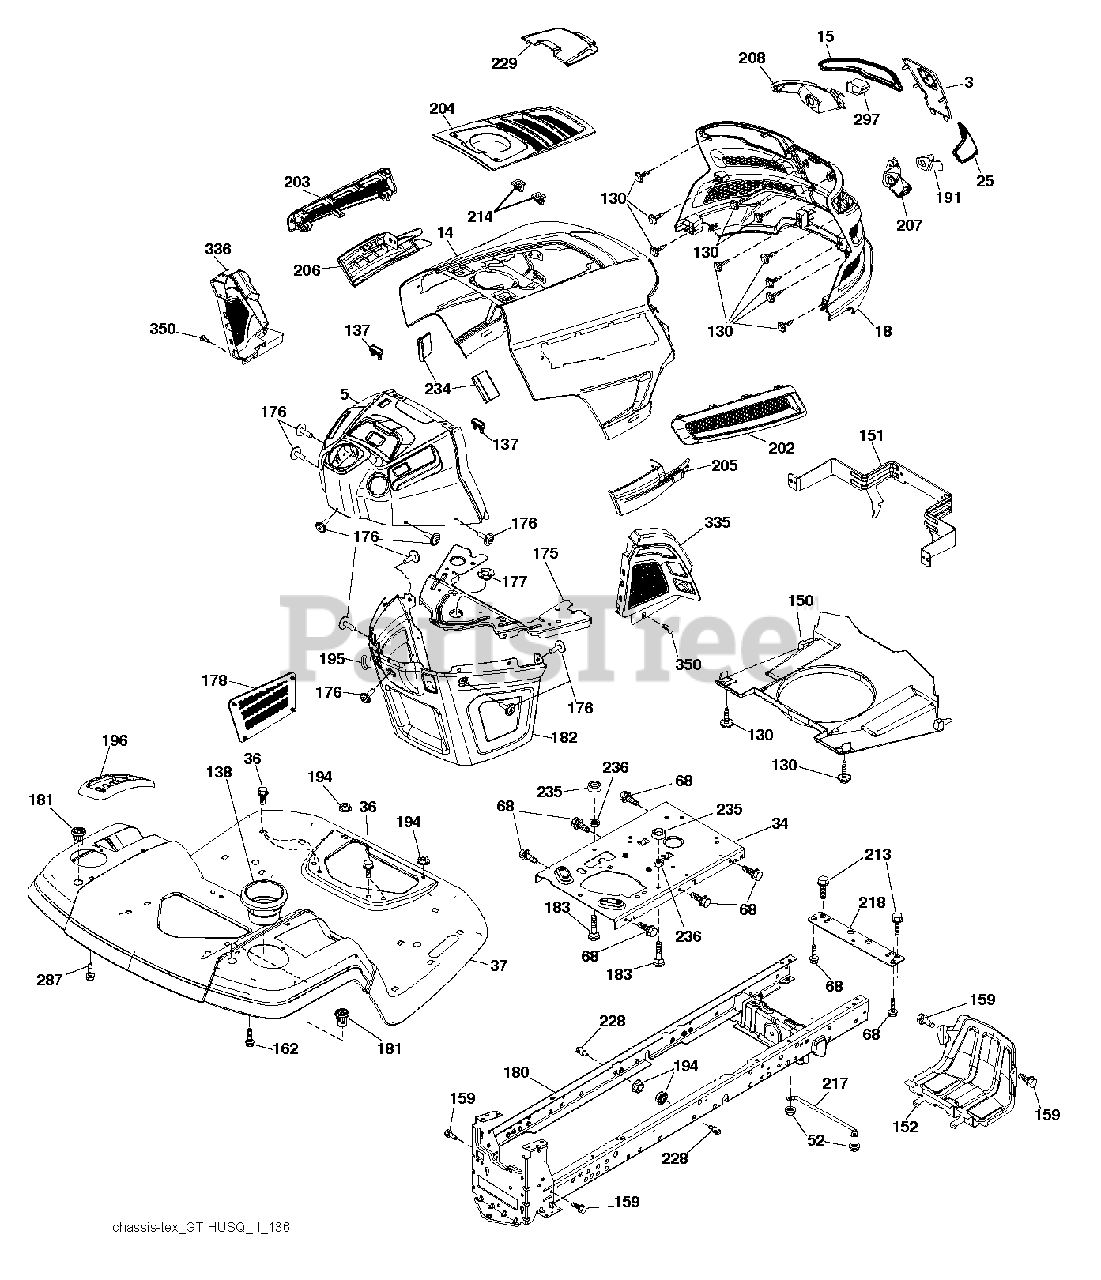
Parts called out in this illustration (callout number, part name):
3	APPLIQUE.SUBASM.GT.HUSQ.II
5	DASH.UPR.GT2.SRV.MIND.MAN.CLUT
14	HOOD.ASM.HUSQVARNA.GT.TEX.ORAN
15	LENS.HEADLIGHT.LH.GTII.2011
18	GRILLE.SUBASM.GT.HUSQ.II
25	LENS.HEADLIGHT.RH.GTII.2011
34	PLATE.ENGINE.WELDED.CHASSIS
36	SCREW 5/16"
37	FENDER.TLT.PDL.CNTRL.W/CPH.ORG
52	LOCKNUT
68	SCREW LT
130	SCREW.#10 X 0.750.BOS
137	BUMPER DASH
138	HOLDER.CUP.LT.GREY
150	AIR DUCT.GTV2(1.66"RING HEIGHT
151	BRACKET.PIVOT.HOOD.GT.HUSQ.II
152	SHIELD.BROWNING.PNT.GT.V2
159	SCREW, 3/8-16X3/4
162	SCREW.HI-LO.CONSOLE
175	PLATE.CROSSMEMBER.HUSQ
176	SCREW.#10-24X5/8.RN.QU
177	BUSHING, STEERING
178	CARGO.ASM.NET.TXGT.W/C
180	CHASSIS
181	BUSHING.MNT.FEND.CRGO.TEX.49
182	DASH.LOWER.COMMON.12V.ADAPTOR
183	BOLT.5/16-18X1-1/4 FULL THD
191	INSERT.REFLECTIVE.RH.HUSQ.GTII
194	NUT LOCK HEX FLANGE 5/16-18
195	PLUG.HOLE.DASH.LOWER.12V.BLK
196	DECKLFT.CONSOL FULL ASSM GREY
202	VENT.TOP.EXTERNAL.FILL.GT2.GRE
203	VENT.SIDE.LH.GT.HUSQ.II.498
204	VENT.TOP.EXTERNAL.FILL.GT2.GRE
205	SIDE.TRIM.RH.GT.HUSQ.II
206	SIDE.TRIM.LH.GT.HUSQ.II.GRAY
207	BEZEL LIGHT.RH.GT.II.MYLAR
208	BEZEL LIGHT.LH.GT.II.MYLAR
213	BOLT
214	CLIP.RETAINER.TINNER.
217	ROD.PIVOT.HOOD
218	X-PIECE.HOOD.STOP.NON/
228	STUD.FASTNER.W/ANTI-ROTATE
229	LID.EXT.FILL.GT.HUSQ2.BLACK
234	BUMPER.HOOD.TEX.HUSQVARNA
235	SPACER FENDER
236	NUT.CENTERLOCK.5/16-
287	SCREW 1/4X20
297	INSERT.REFLECTIVE.LH.HUSQ.GTII
335	COVER.LOWER.DASH.RH.BLACK
336	COVER-LH.LOWER.DASH.GT2.BLACK
350	CLIP.X-MAS.TREE
